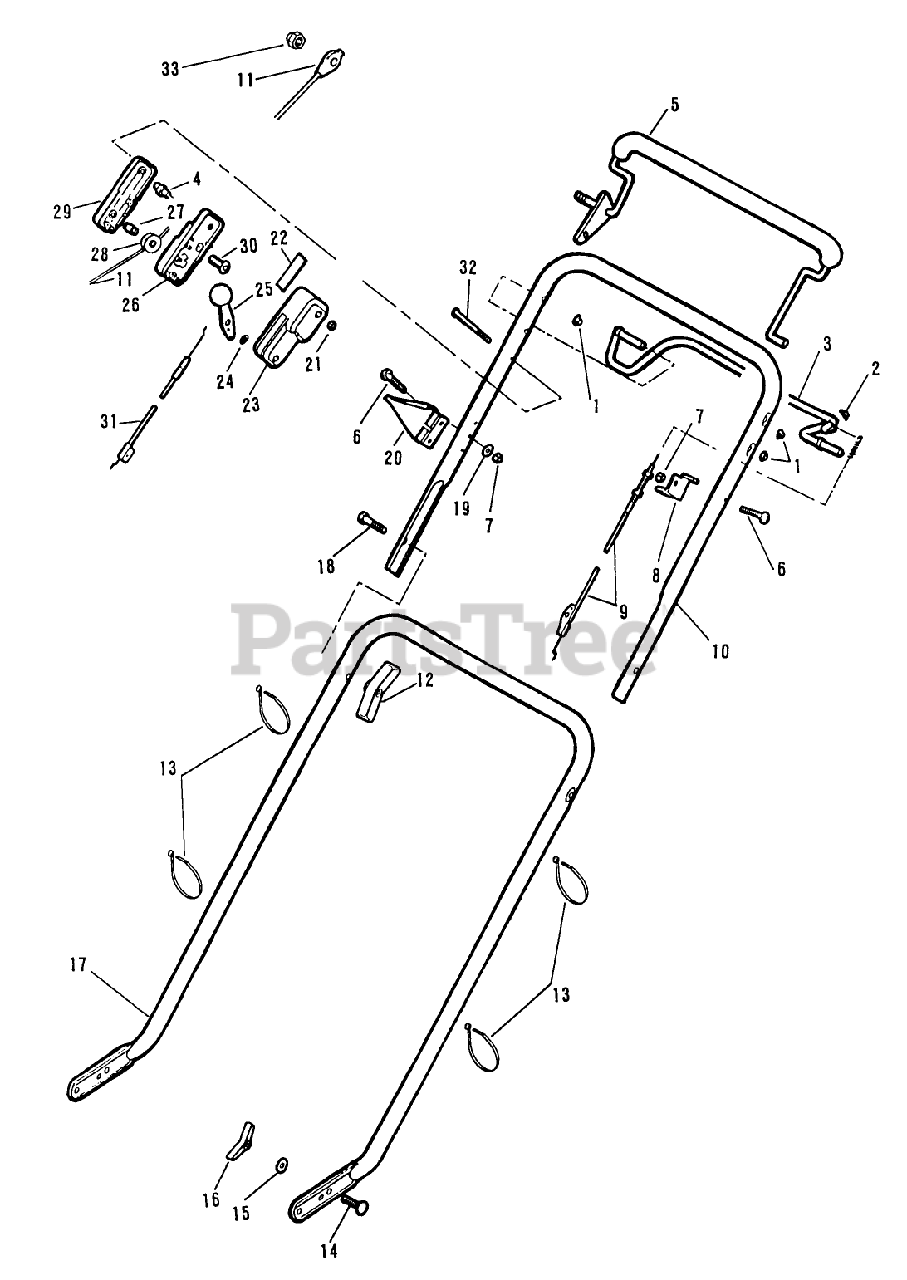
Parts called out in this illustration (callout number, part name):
4	COLUMN
5	CONTROL LEVER ARG
7	LOCKNUT E
8	ANCHOR C'DUIT TRO
9	CABLE - CONTROL
11	CONTROL CABLE
12	NUT-WING
16	NUT WING
19	WASHER
21	NUT C/LOCK E
24	WASHER-SPRING
25	LEVER&KNOB AY WES
27	PIN SKF
28	PULLEY PL
29	OUTER CONTROL CASE
30	SCREW
31	CABLE TH'TTLE WES
32	SCREW
33	NUT ACORN
